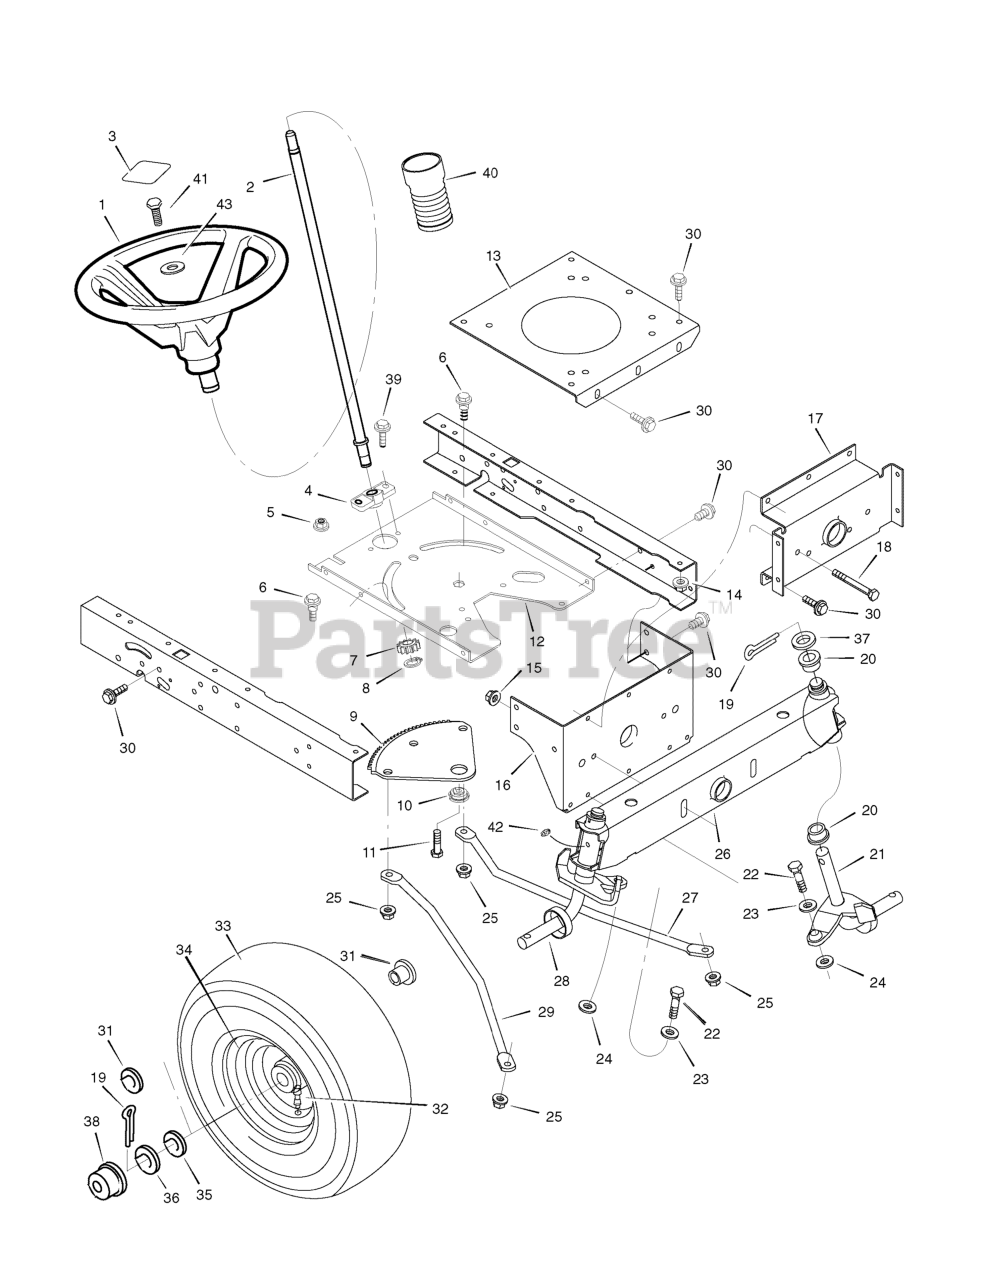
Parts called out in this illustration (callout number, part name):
1	Wheel, Steering 4 Spoke
2	Post, Steering
3	Cover, Steering Wheel
4	Bearing
5	Nut, Flange **
6	Bolt, Shoulder
7	GEAR, Pinion **
8	Ring, Snap **
9	Gear, Sector
10	Bearing
11	CAPSCREW, Hex Head, 5/16-18 x 1
12	Plate, Steering
13	Plate, Engine
14	Nut, Flange
15	Nut, Flange
16	Bracket, Hanger
17	Axle, Hanger
19	Pin, Cotter
20	Bearing
21	Spindle Assembly, Left
22	Bolt
23	Washer
24	Washer
25	Nut, Flange
26	Axle Assembly
27	Drag Link, Left
28	Spindle Assembly, Right
29	Drag Link, Right
31	Bearing, Wheel
32	Stem, Valve
34	Wheel andTire Assembly
38	Hub Cap
40	Bellows
41	Screw, Hex
42	Fitting, Lube
43	Washer
